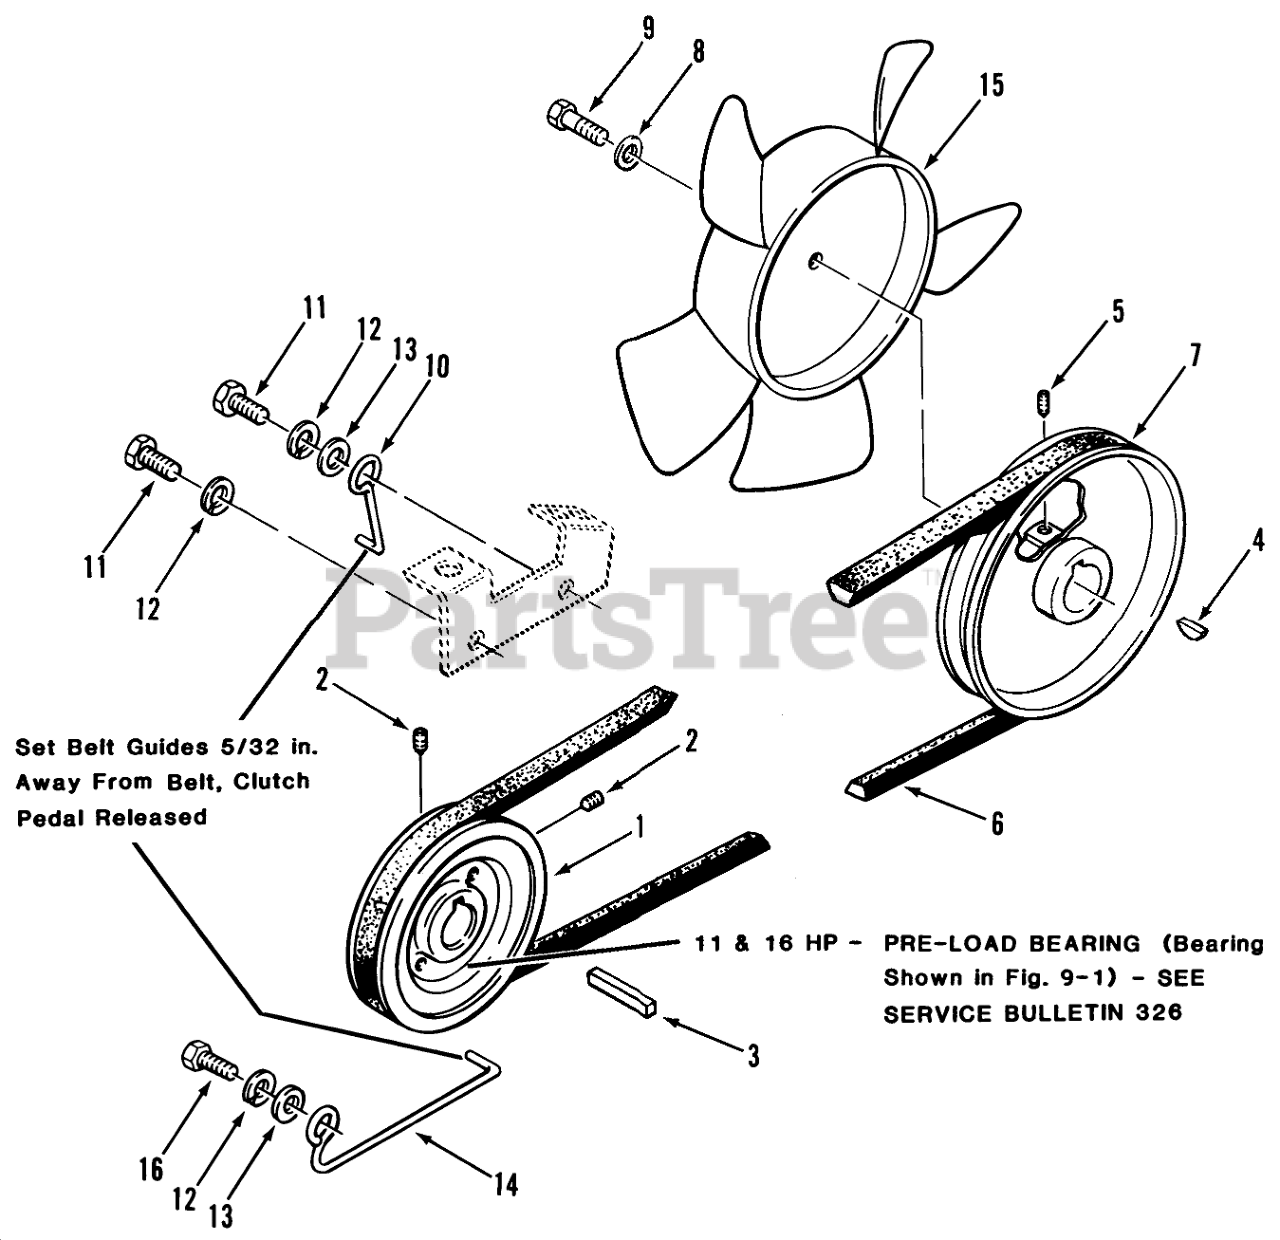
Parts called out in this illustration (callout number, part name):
1	Engine Drive Pulley GT-1848 Only
1	PULLEY
2	Set Screw
4	KEY-WOODRUFF
4	KEY-HI PRO
5	Set Screw
6	V-BELT TRANS DRIVE
6	V BELT
6	Belt-Drive
7	PULLEY
7	PULLEY-TRANSMISSION
8	WASHER
9	H H C S
10	Belt Guide-Top
11	BOLT
12	LOCKWASHER
13	Washer
14	Belt Guide-Bottom
14	GUIDE-BELT
15	NYLON FAN-L-CW
16	Bolt
